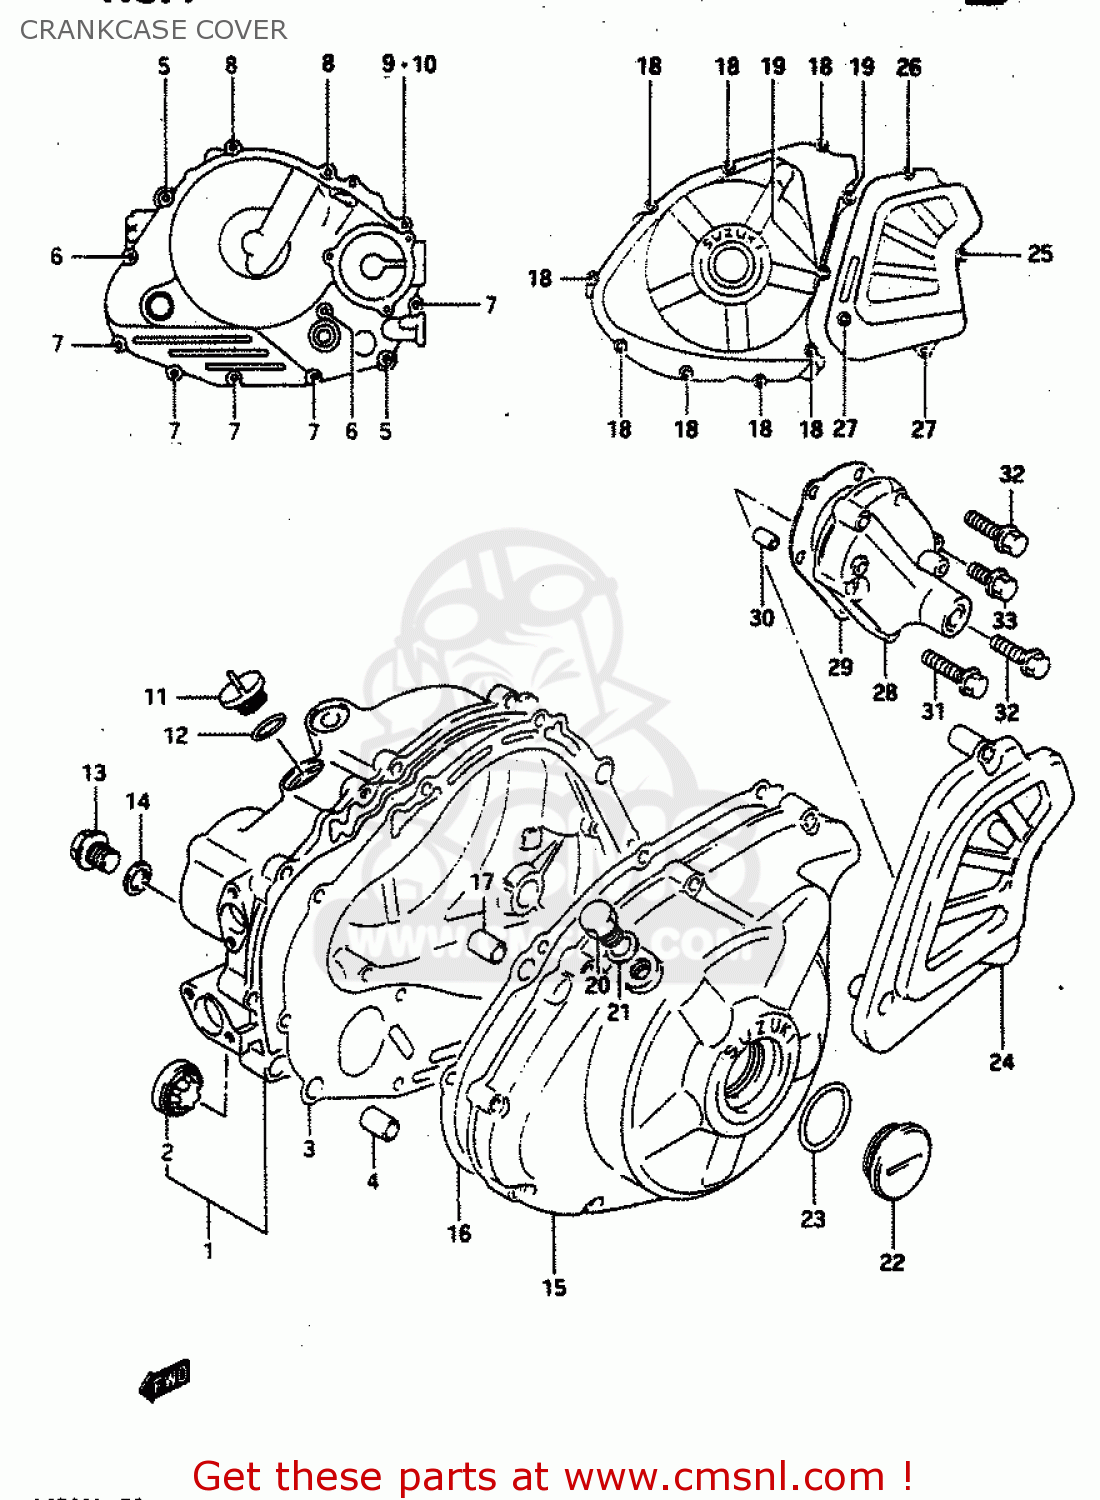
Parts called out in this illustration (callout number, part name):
1	COVER,CLUTCH
2	LENS,OIL LEVEL CHECK
3	GASKET,CLUTCH COVER
4	PIN
5	BOLT 6X50
6	BOLT 6X40
7	BOLT 6X35
8	BOLT 6X25
9	BOLT 6X25
10	WASHER
11	PLUG
12	O RING(D:3.1,ID:16.8)
13	PLUG(14X12)
14	GASKET(14X19.2X2) (NAS)
15	COVER,GENERATOR
16	GASKET,MAGNETO COVER (MCA)
17	PIN
18	BOLT 6X30
19	BOLT 6X25
20	PLUG(12X9)
21	GASKET(12.1X16.2X3.7) (NAS)
22	PLUG
23	O RING(D:3.1,ID:32.7)
24	COVER,ENGINE SPROCKET
25	BOLT
26	BOLT 6X35
27	BOLT 6X20
28	COVER,GEAR SHIFT
29	GASKET,GEAR SHIFT COVER (MCA)
30	PIN
31	BOLT 6X35
32	BOLT 6X30
33	BOLT 6X20
